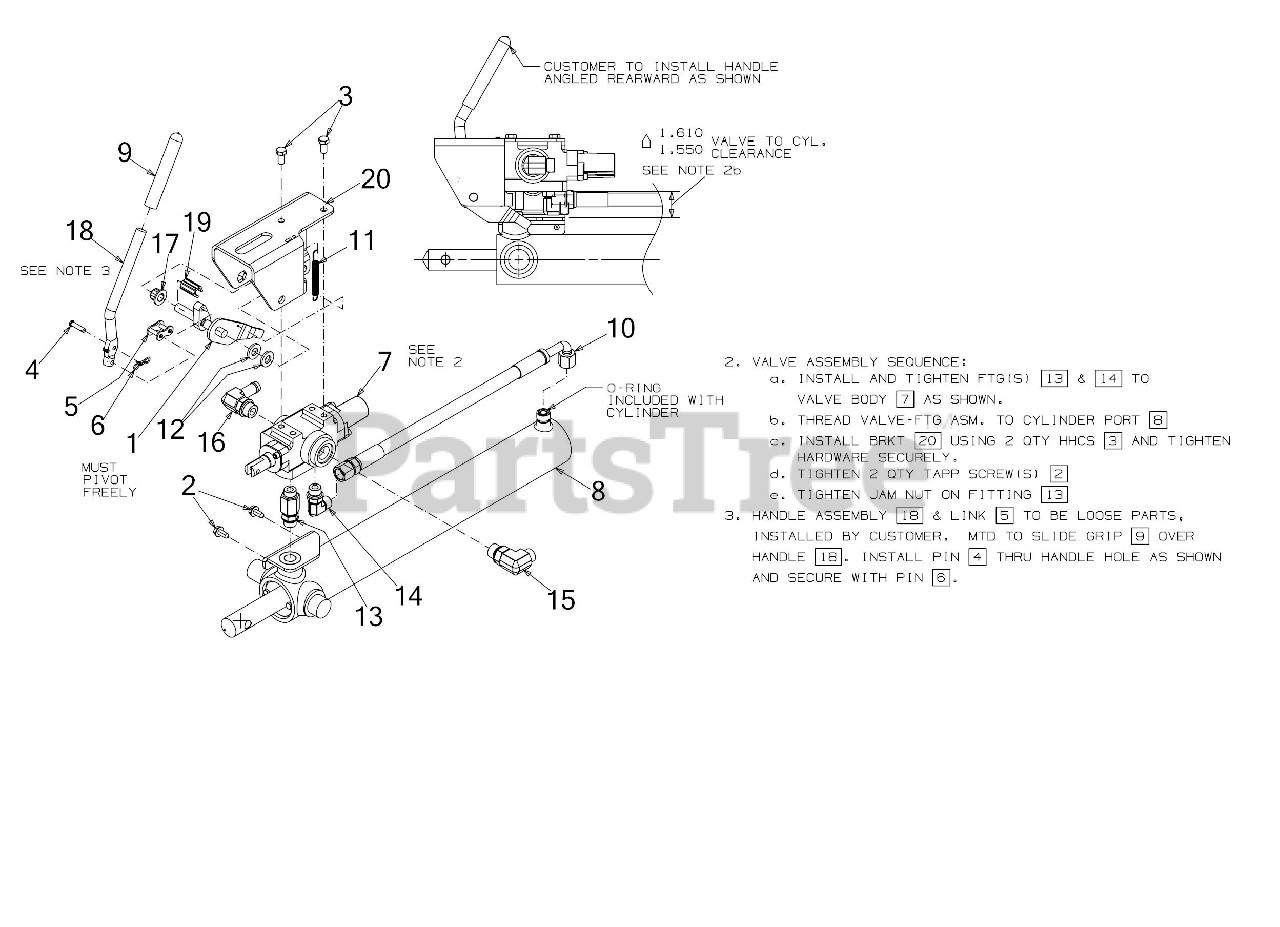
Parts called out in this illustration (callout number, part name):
1	HANDLE PIVOT ARM ASSEMBLY
2	SCREW 5/16-18 x .750
3	SCREW 3/8-16 x .75 GR 5
4	CLEVIS PIN .25 x 1.00
5	VALVE HANDLE LINK
6	BOW TIE COTTER PIN 1/4-5/16
7	CONTROL VALVE FLEX
8	LOGSPLITTER CYLINDER
10	HYDRAULIC HOSE
11	EXTENSION SPRING
12	FLAT WASHER .510 x 1.000 x .125
13	HYDRAULIC FITTING
14	HYDRAULIC FITTING
15	90 DEGREE HYDRO FITTING 7/8 ORB x 13/16
16	HYDRAULIC FITTING 7/8 ORB
17	HEX FLANGE BEARING .506ID x .590LG
18	CONTROL VALVE HANDLE
19	SPACER CLIP
20	CONTROL VALVE BRACKET
